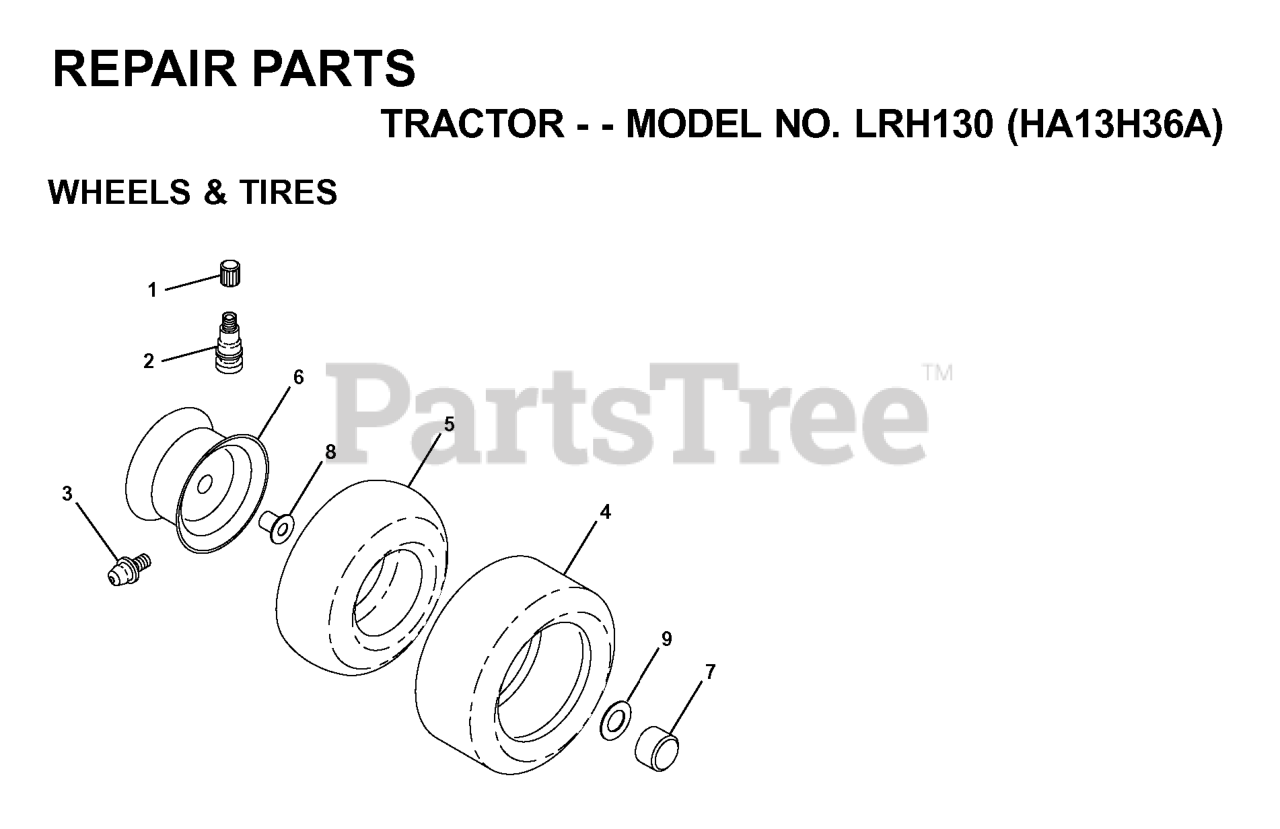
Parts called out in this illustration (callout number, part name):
2	VALVE STEM LT
3	FITTING LT
4	TIRE FRONT 15X6-6
5	TUBE.16X6.5/7.5-8
5	TUBE.5.3/4.5/6
6	RIM
6	RIM REAR 8"
7	CAP.HUB.FRONT.LT.BLACK
8	BEARING T
